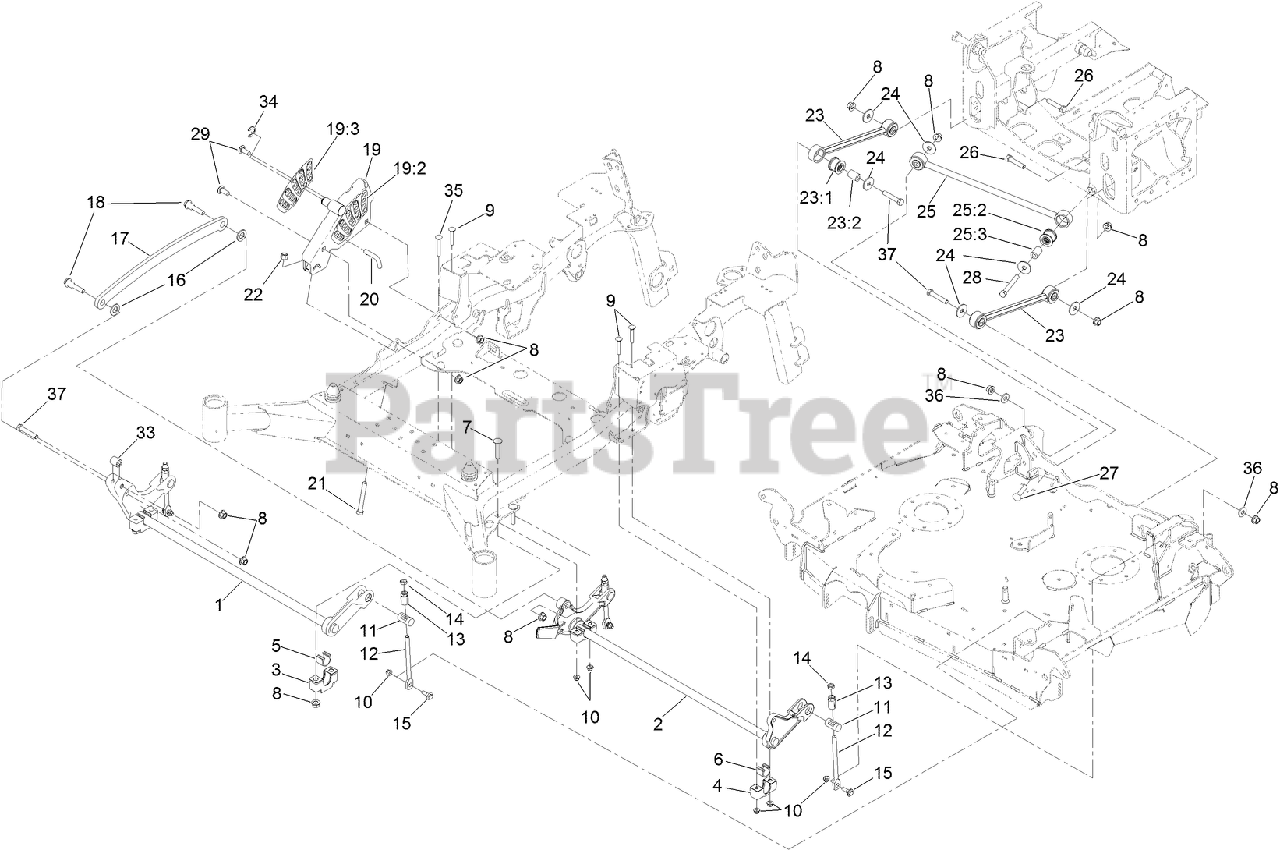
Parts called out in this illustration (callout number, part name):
1	DECKLIFT-FRONT
2	LIFT-DECK, REAR
3	SUPPORT-CROSS SHAFT, BEARING
4	SUPPORT-CROSS SHAFT, BEARING REAR
5	BEARING-CROSS SHAFT, FRONT
6	BEARING-CROSS SHAFT, REAR
7	BOLT-CARR
8	NUT-LOCK
9	SCREW-HH
10	NUT-HF, NI
11	TRUNNION
12	LINK-ADJUSTER, DECK LIFT
13	ADJUSTER-LIFT, DECK
14	NUT-JAM
15	SCREW-SHOULDER, HHF
16	WASHER-FLAT
17	LINK-LIFT, DECK
18	SCREW-HHF, SHOULDER
19	HOC ASM
19:2	DECAL-HEIGHT OF CUT
19:3	DECAL-HEIGHT OF CUT, OUTER
20	PIN-HOC
21	BOLT-TAP
22	NUT-LOCK, NI
23	DECK STRUT ASM
23:1	BUSHING-SUSPENSION, RUBBER
23:2	SPACER
24	WASHER-THRUST
25	PANHARD ROD ASM
25:2	BUSHING-SUSPENSION, RUBBER
25:3	SPACER
26	SCREW-HH
27	SCREW-CARR
28	SCREW-HH
29	SCREW-CARR, SHORT NECK
33	SPACER-PIVOT
34	RING-RETAINING
35	SCREW-HH
36	WASHER-SPRING
37	SCREW-HH
